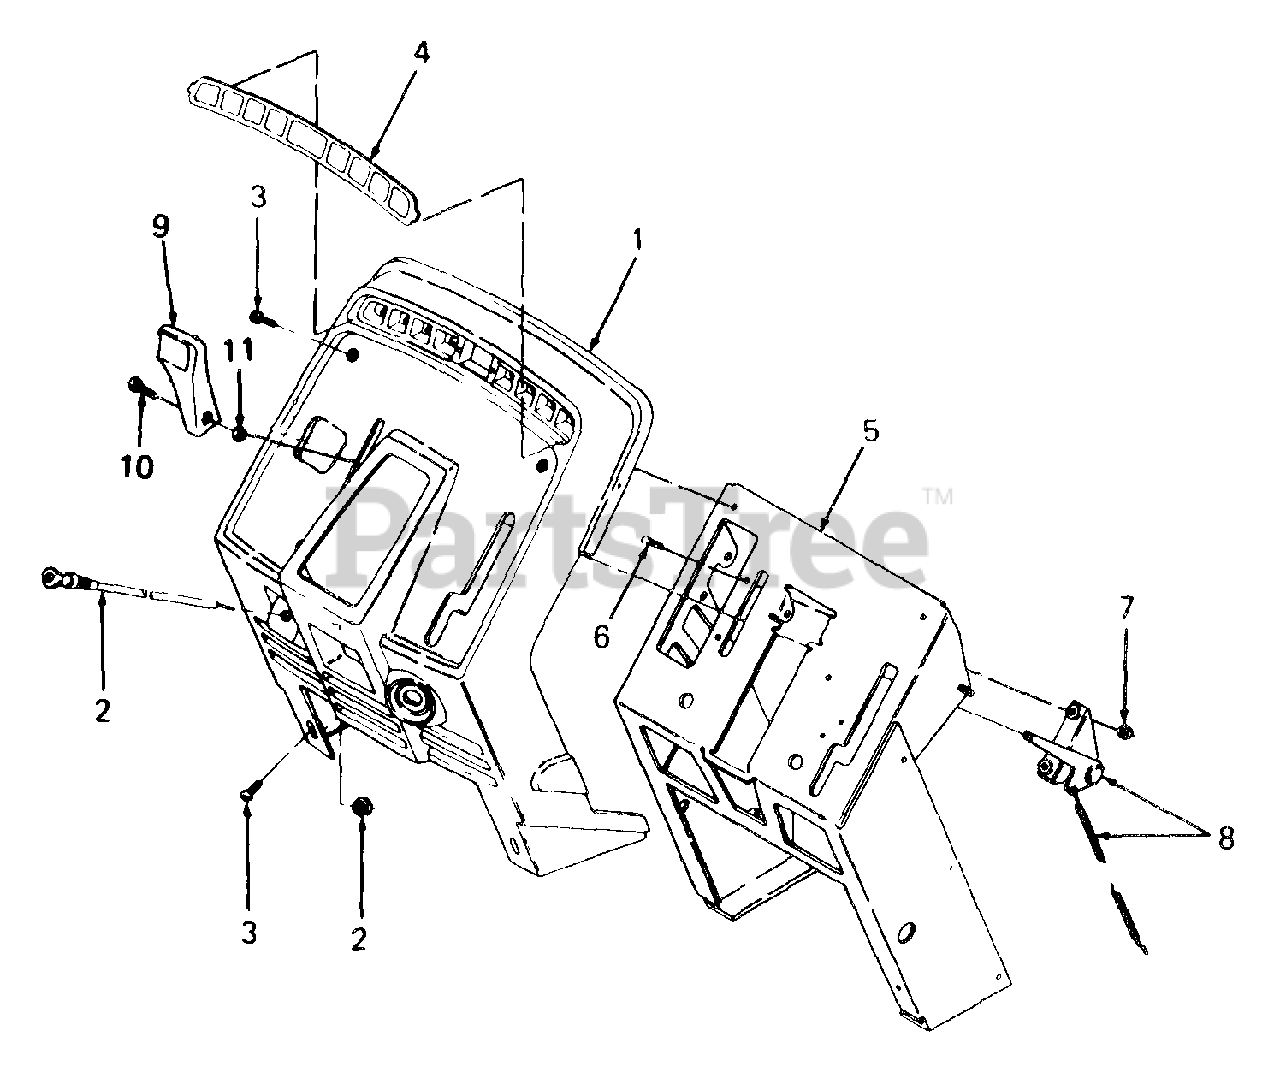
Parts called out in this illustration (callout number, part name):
1	Panel, Instrument
2	Choke Cable w/Nut
3	Screw, Pan Hd Cutting #10-24 X .75 Lg
4	Label, Dash
7	Nut, Hex Keps, #10-32
8	Control, Throttle
9	Knob, Throttle
10	Screw, Cross Rec Truss Hd, #8-32 X .38 Lg
11	Nut, 8-32
